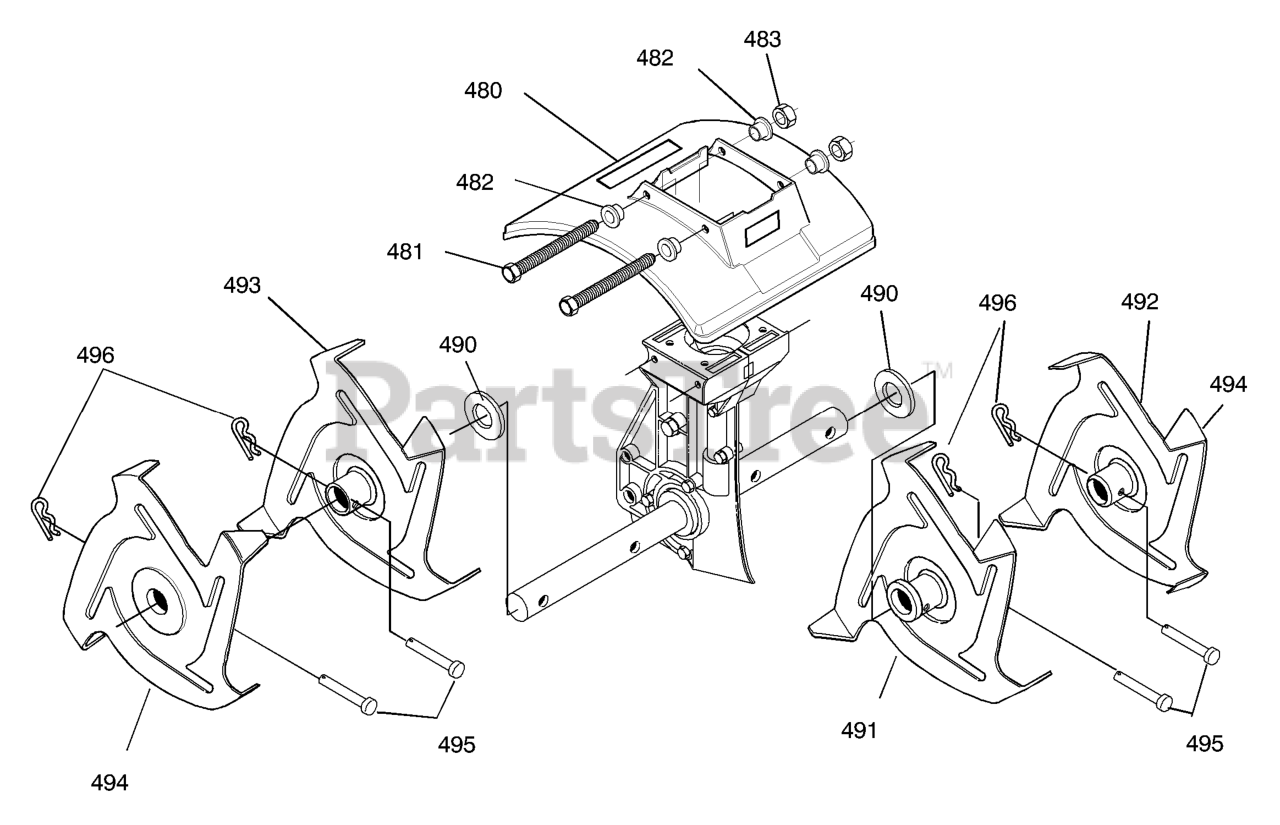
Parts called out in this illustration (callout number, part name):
480	Shield, Tine
481	Screw, 1/4-20x5.50
482	Spacer, Flange
483	Nut, 1/4-20
484	Decal, Murray
485	Decal, Caution
490	Washer, Felt
491	Tine Assy. Inner LH
492	Tine Assy. Outer LH
493	Tine Assy. Inner RH
494	Tine Assy. Outer RH
495	Clevis Pin
496	Hair Pin
